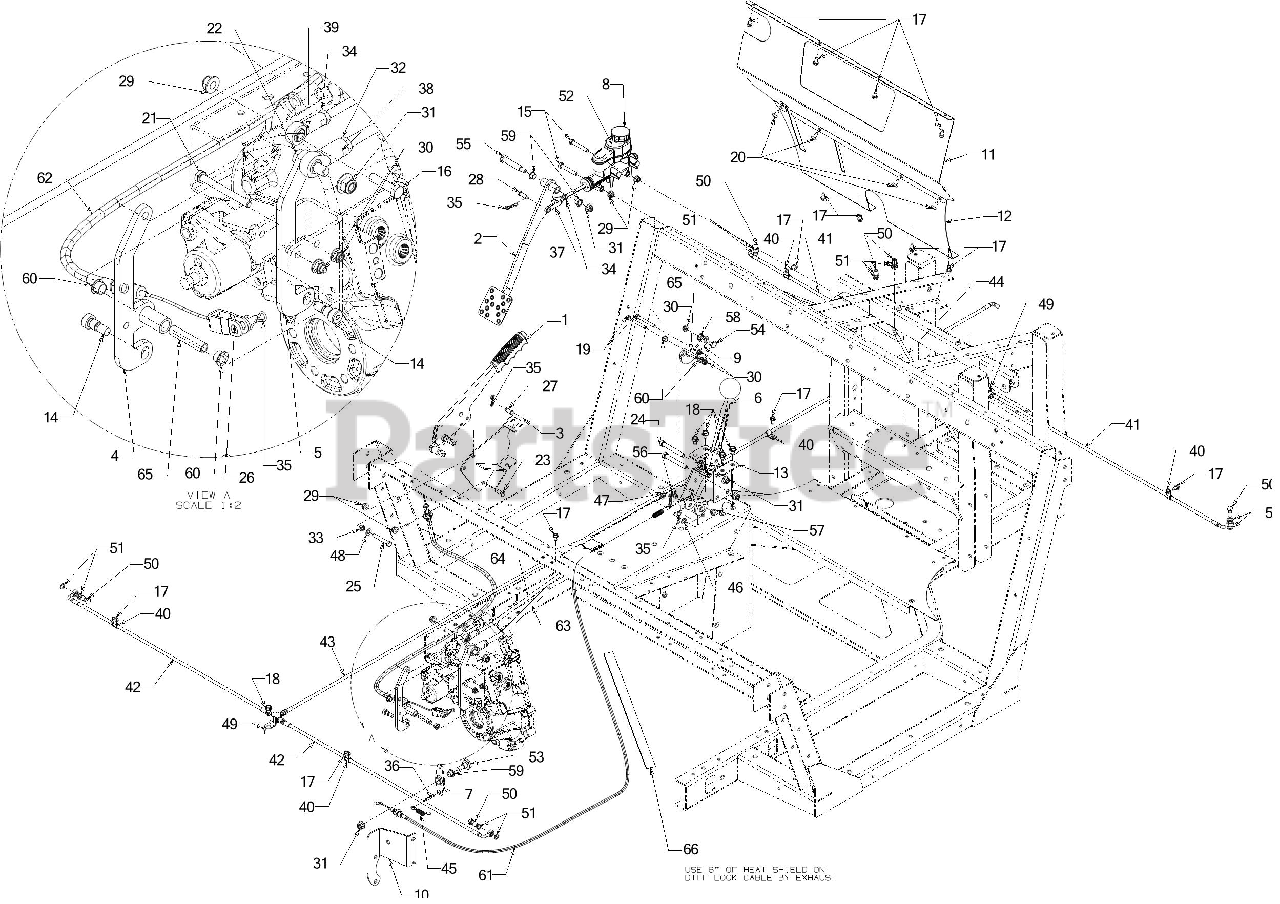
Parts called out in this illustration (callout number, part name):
1	LEVER ASSEMBLY:BRAKE
2	BRAKE PEDAL ASSEMBLY
3	PARK BRAKE BRACKET ASSEMBLY
4	HI-LO SHIFT LEVER ASSEMBLY
5	FNR HI-LO SHIFT LEVER ASSEMBLY
6	HURST SHIFT ASSEMBLY
7	DIFF LOCK LEVER ASSEMBLY
8	MASTER CYLINDER ASSEMBLY
9	OVER CENTER PAWL PLATE
10	DIFFERENTIAL CABLE BRACKET
11	UPPER DASH PANEL
12	LOWER DASH PANEL
13	CONSOLE SHAFT MOUNTING
14	SHOULDER SCREW .372 x .375 x 5/16-18
15	SCREW-HEAD PATCH GR5 5/16-18X2"
16	SCREW 5/16-18 x 1.25 GR5
17	SCREW 1/4-20 X.500
18	SCREW 5/16-18 x .500
19	SCREW 1/4-20 x 2.25 GR5
20	SCREW 1/4-14 x .625
21	SCREW 1/4-20 x 2.50 GR5
22	SCREW 3/8-16 x 1.25 GR5
23	SCREW 5/16-18 x .75 GR5
24	SCREW 3/8-16 x 2.75 GR5
25	SCREW 5/16-18 x 2.0 GR5
26	CLEVIS PIN .25 x 1.00
27	CLEVIS PIN 5/16 x 3/4
28	CLEVIS PIN .312 x 1.0
29	FLANGE LOCK NUT 5/16-18
30	FLANGE LOCK NUT
32	HEX JAM NUT 3/8X24
33	HEX NUT
34	HEX JAM NUT 5/16-24 GR 5
35	BOW TIE COTTER PIN 1/4-5/16
37	ADJUSTABLE ROD END
38	ROD END 3/8 ID
39	ROD END 5/16 ID
40	HOSE CLAMP
41	FRONT BRAKE HOSE
42	REAR BRAKE HOSE
43	BRAKE MASTER CYLINDER HOSE (REAR)
44	BRAKE MASTER CYLINDER HOSE (FRONT)
46	FLAT WASHER
47	FLAT WASHER
48	FLAT WASHER
49	TEE FITTING
50	BANJO FITTING
51	BANJO FITTING
53	SHOULDER BOLT .50X.434 EXP
54	SHOULDER SCREW .375X.380:1/4-20
55	SHOULDER SCREW .50 x 2.23 3/8-16
56	FLANGE BEARING
57	FLANGE BEARING
58	BUSHING .380 ID
59	NYLINER BEARING
60	FLANGE BEARING
61	DIFF LOCK CONTROL CABLE
62	PARK CONTROL CABLE
63	F-N-R SHIFT LINK
64	HI/LO SHIFT LINK
65	DIFF LOCK PIVOT SPACER
66	HEAT SHIELD
